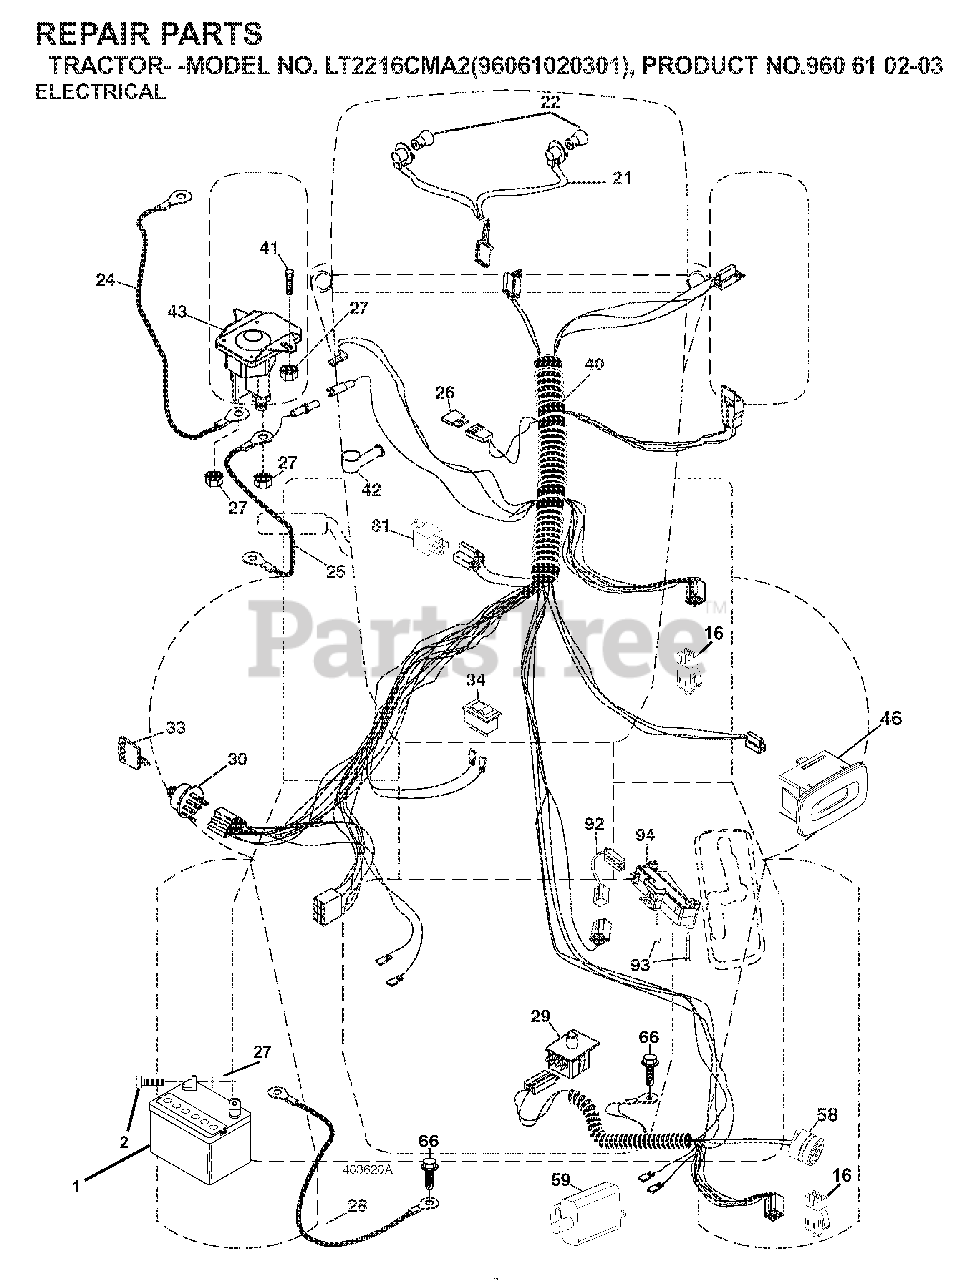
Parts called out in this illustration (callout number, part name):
1	BATTERY 12V .35 AMP
16	SWITCH INTERLOOK PUSH-IN
21	HARNESS ASSY LIGHT
22	LIGHTBULB
24	BATTERY CABLE GT
25	CABLE BATTERY
26	FUSE 20AMP
27	NUT
28	CABLE GROUND
29	SWITCH.SEAT.DP W/RAMPS
30	SWITCH.IGN.DELTA.W.LGH.ROS
33	KEY MLD GEN DELTA
34	SWITCH LT
42	TERMINAL COVER
43	SOLENOID.W/BRASS.PLUNG
46	GUAGE.SRVCMNDR.HRMTR.
58	BUZZER
81	RELAY.ASSY.T
92	HARNESS.PIGTAIL.CONSLE
93	SCREW.PLASTITE
94	MODULE.REVERSE.ROS
